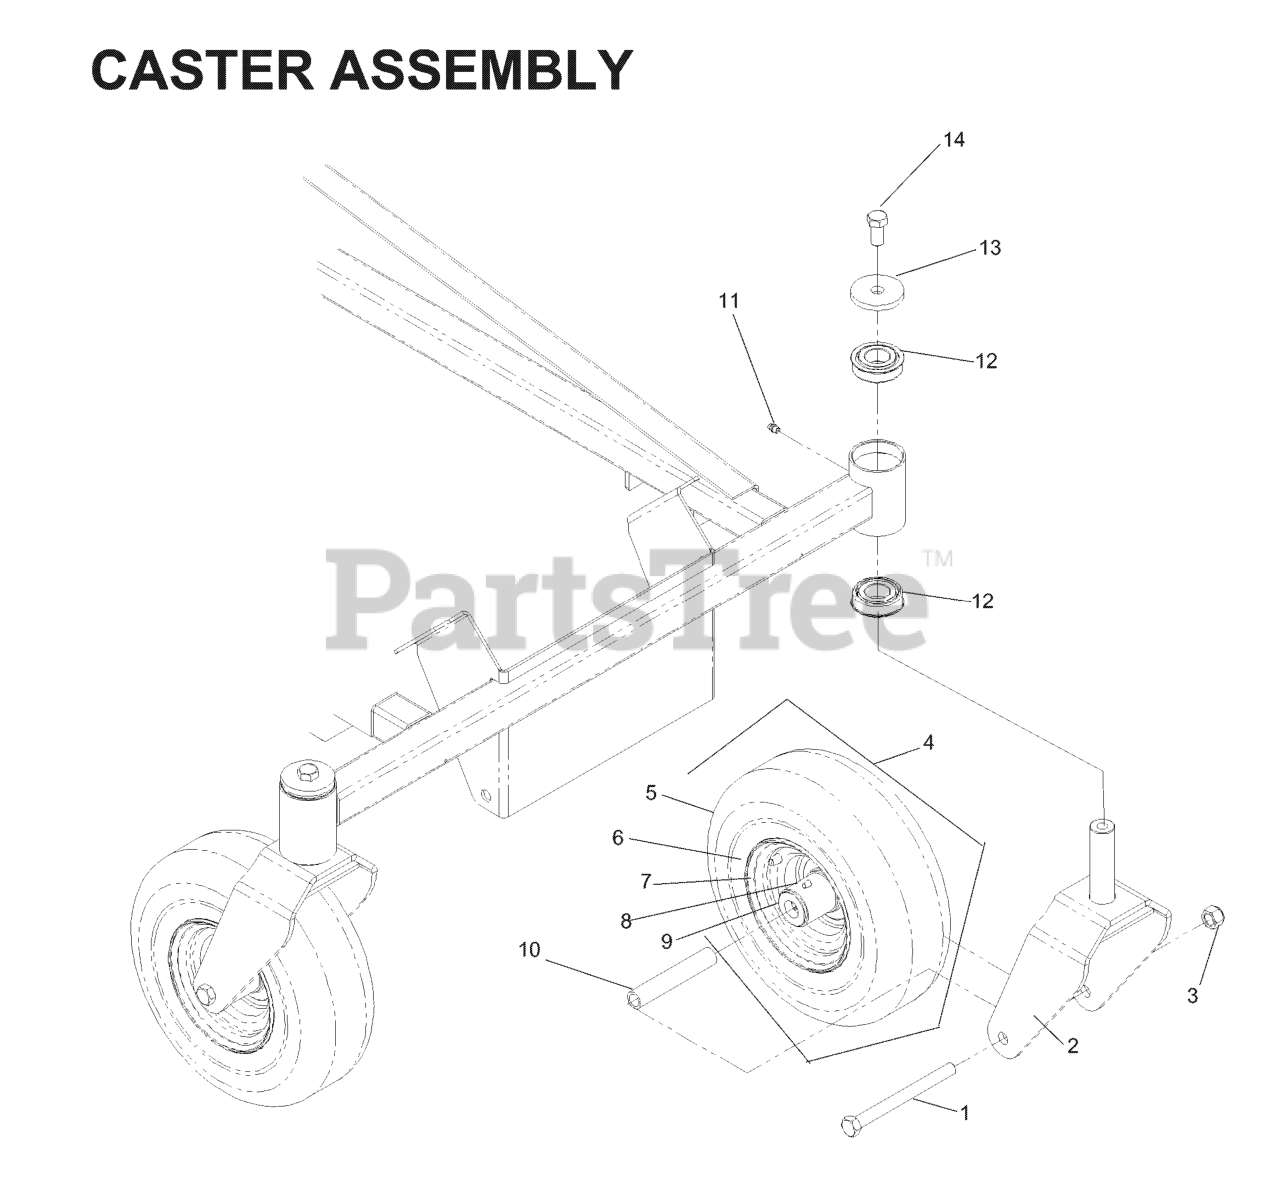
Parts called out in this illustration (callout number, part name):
1	HCS 1/2C X 5 1/2
2	CASTER YOKE - PAINTED
3	NUT 1/2-13 HEX NYLOC ZD
4	TIRE/WHEEL.CASTER
5	TIRE - CASTER
6	VALVE STEM TR-412
8	ZERK
9	BEARING RETAINER
12	BEARING FLANGED
13	HEAVY WASHER
14	HHCS 1/2-13 X 1
